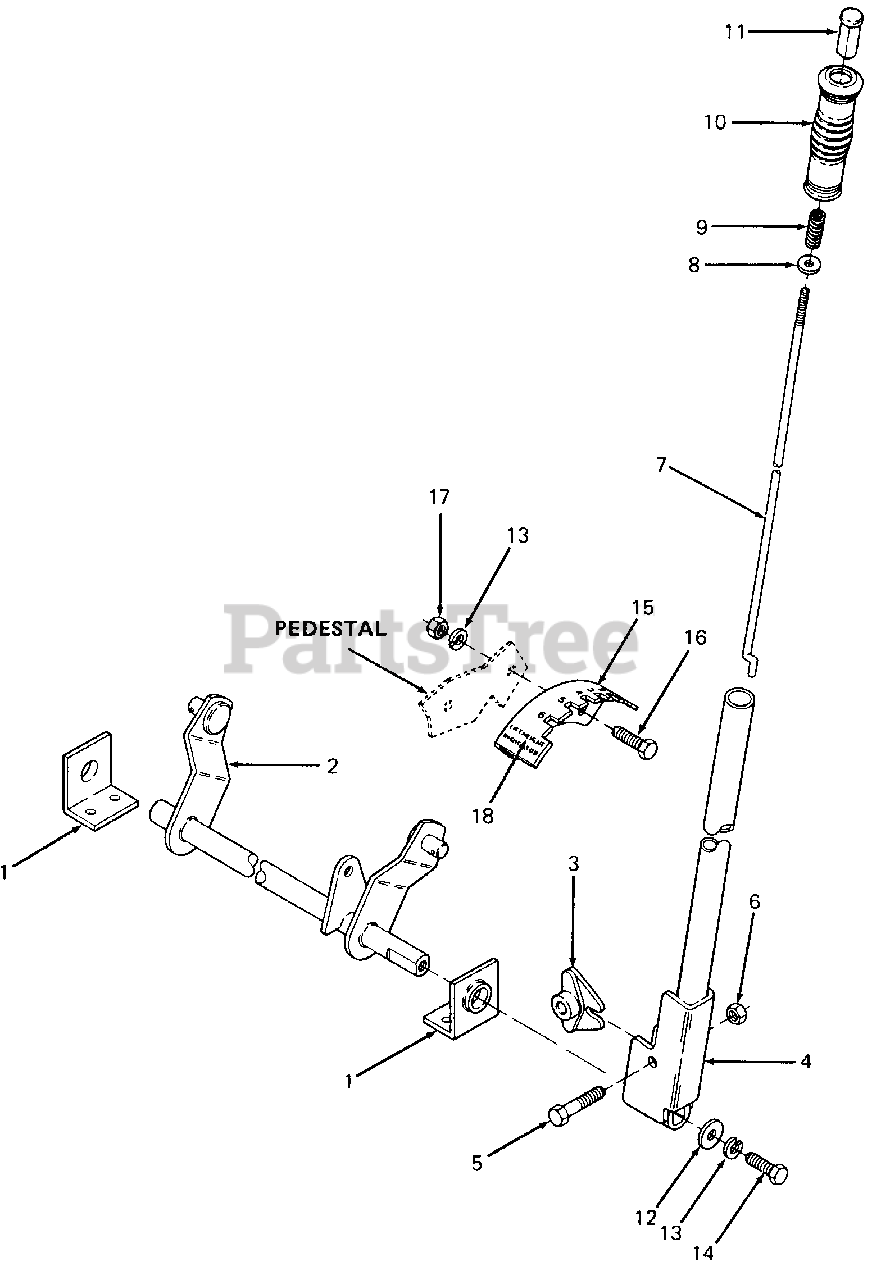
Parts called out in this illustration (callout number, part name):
1	Bracket, Lift Shaft
2	Shaft Assy, Lift
3	Kit, Index Pawl
4	Handle, Lift
5	Screw, Hex, 3/8-16 X 1.62 Lg
6	Nut, Hex Center Lock Jam, 3/8-24
7	Rod, Index
8	Washer, Flat, .260 X .720 X .06
10	Grip, Lift Handle
11	Button, Handle
12	Washer, Flat, .345 X 1.0 X .100 Thk
13	Washer, Lock, 5/16
14	Screw, Hex Cap, 5/16-24 X .75 Lg
17	Nut, Hex, 5/16-18 GR5
18	Label, Height Indicator
